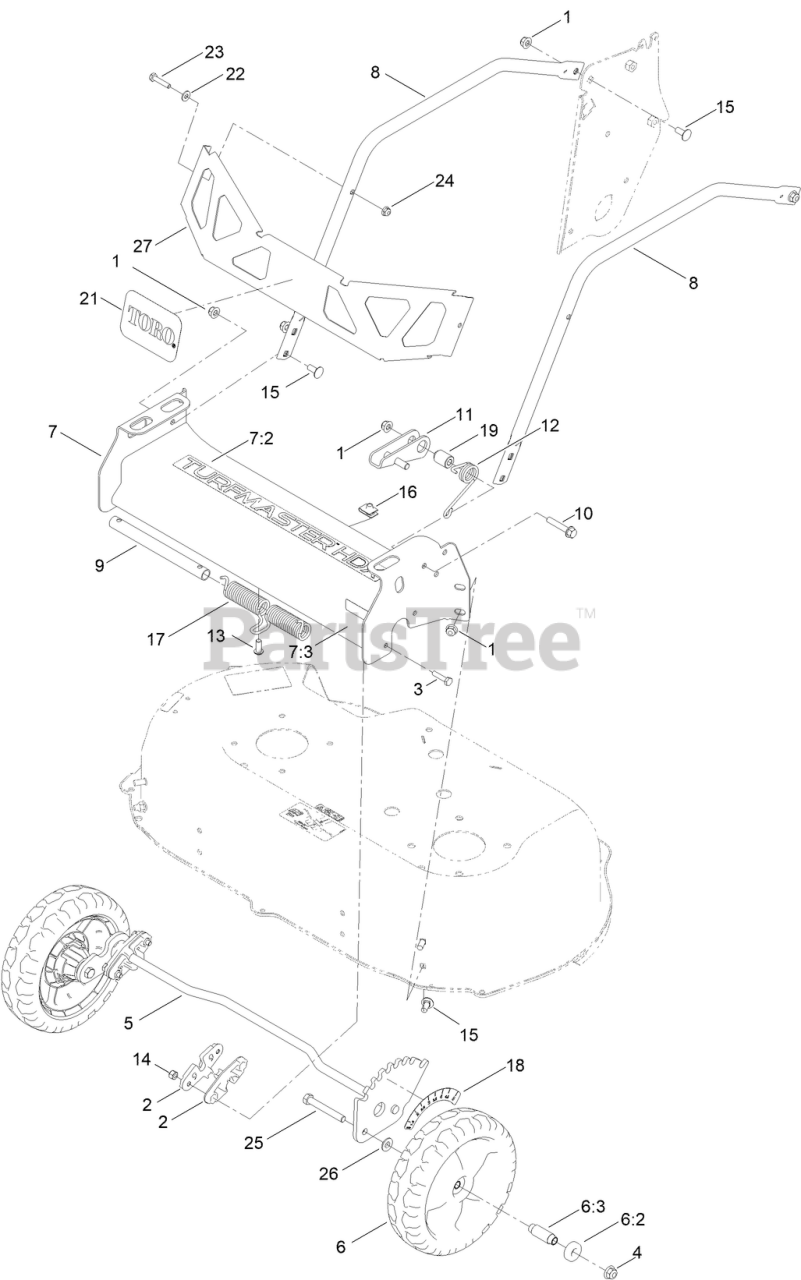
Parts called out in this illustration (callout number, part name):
1	NUT-HF, NI
2	BUSHING-FRONT
3	SCREW-HH
4	NUT-HF, NI
5	FRONT AXLE ASM
6:2	BEARING-BALL
6:3	SPACER
7	FRONT BUMPER ASM
7:3	DECAL-WARNING
9	MANDRELL-SPRING
10	SCREW-HWH
11	LOCK-HEIGHT, ADJ
12	SPRING-TORSION
13	SCREW-HSBH
14	NUT-LOCK, NI
15	SCREW-CARR
16	NUT-U
17	SPRING-TORSION
18	DECAL-HOC, FRONT
19	SPACER
22	WASHER-FLAT
23	SCREW-HH
24	NUT-HF
25	SCREW-HH
26	SPACER-COVER, WHEEL
27	GUARD-ENGINE
